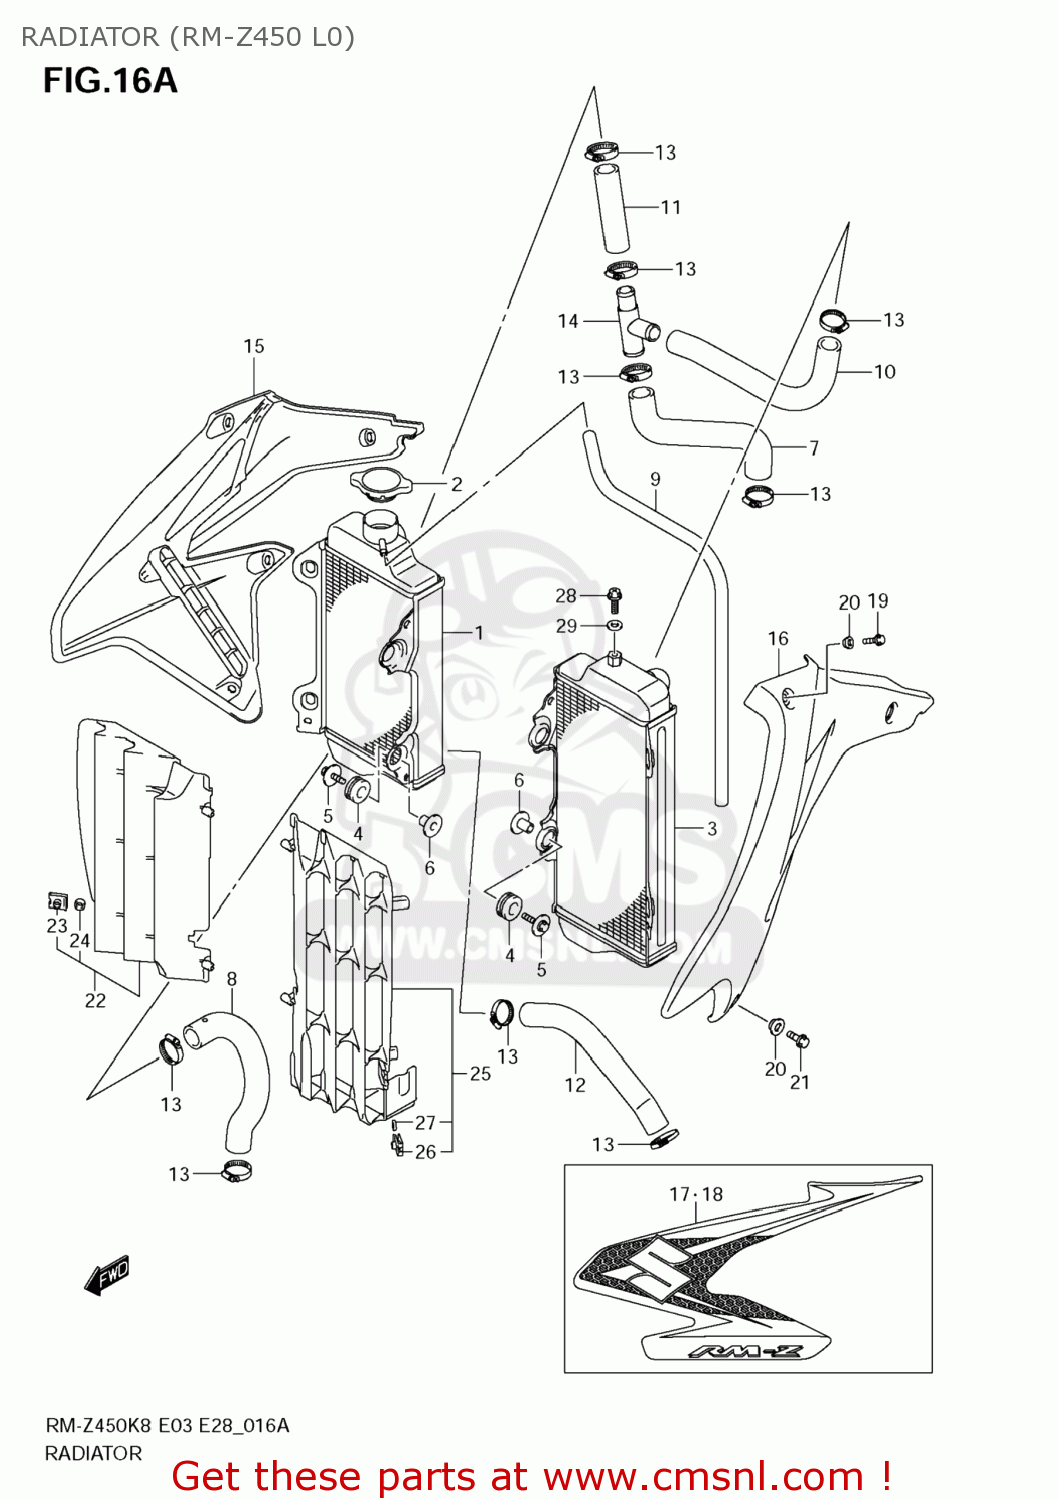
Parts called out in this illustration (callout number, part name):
1	RADIATOR,WATER
2	CAP COMP,RADIATOR
3	RADIATOR,WATER,L
4	CUSHION,RADIATOR LWR
5	BOLT(6X25)
6	SPACER(6.5X10.5X14.1)
7	HOSE,RADIATOR INLET
8	HOSE,RADIATOR OUTLET
9	HOSE(5X8X1000)
10	HOSE,RADIATOR JOINT UPR NO.1
11	HOSE,RADIATOR JOINT UPR NO.2
12	HOSE,RADIATOR JOINT LWR
13	CLAMP
14	JOINT,RADIATOR HOSE
15	COVER,RADIATOR,R
16	COVER,RADIATOR,L
17	TAPE,RADIATOR COVER,R
18	TAPE,RADIATOR COVER,L
19	BOLT(6X12)
20	WASHER
21	BOLT(6X16)
22	LOUVER,RADIATOR,R
23	NUT
24	SPACER(6.2X10X2.2)
25	LOUVER,RADIATOR,L
26	NUT
27	SPACER(6.2X10X2.2)
28	UNION BOLT,AIR VENT
29	GASKET(6.4X11.5X0.8) (NAS)
